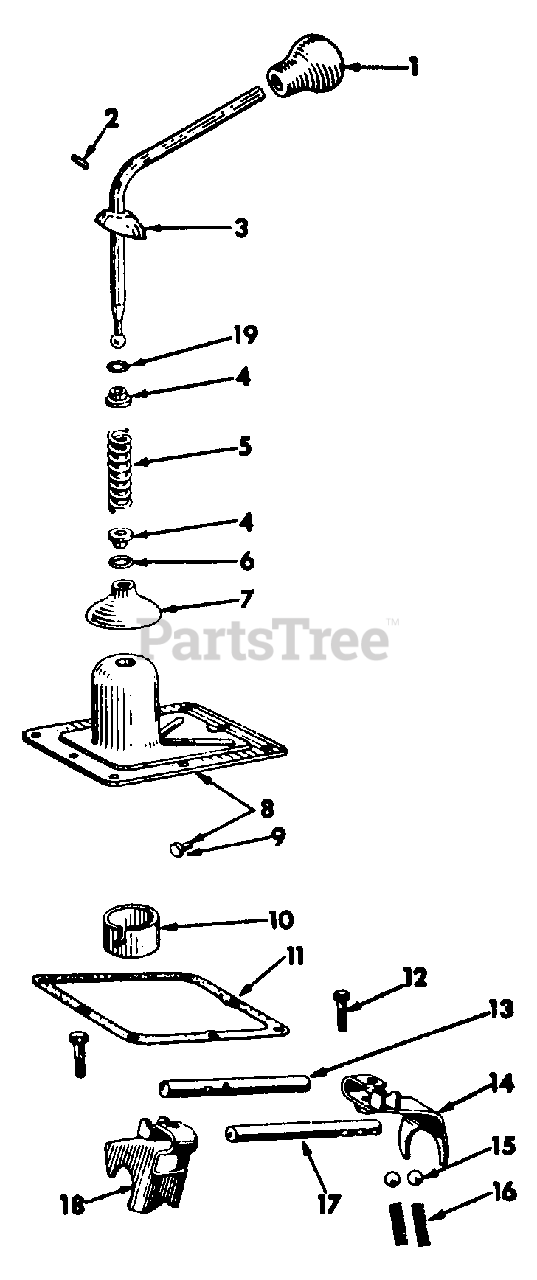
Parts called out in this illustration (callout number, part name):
1	Knob w/Product Graphic, Shift Handle
2	Pin, Gear Shift Swivel Spring Retainer
3	Lever Assy, Gear Shift
4	Retainer, Gear Shift Swivel Spring
5	Spring, Gear Shift Lever
6	O-Ring, 1/2 X 5/8 X 1/16
7	Shield, Gear Shift Lever
8	Housing Assy, Gear Shift Lever
9	Pin, Gear Shift Lever Swivel Stop
10	Guide, Gear Shift Lever
11	Gasket, Gear Shift Lever Housing
12	Screw, Shifter Fork
13	Rod, Second and Third Gear Shifter
14	Package, Second and Third Shifter Fork Service
15	Ball, 3/8 Cr-Stl Grade 3
16	Spring, Gear Shifter Poppet
17	Rod, First and Reverse Gear Shifter
18	Package, First and Reverse Shifter Fork Service
19	Not used in this application
